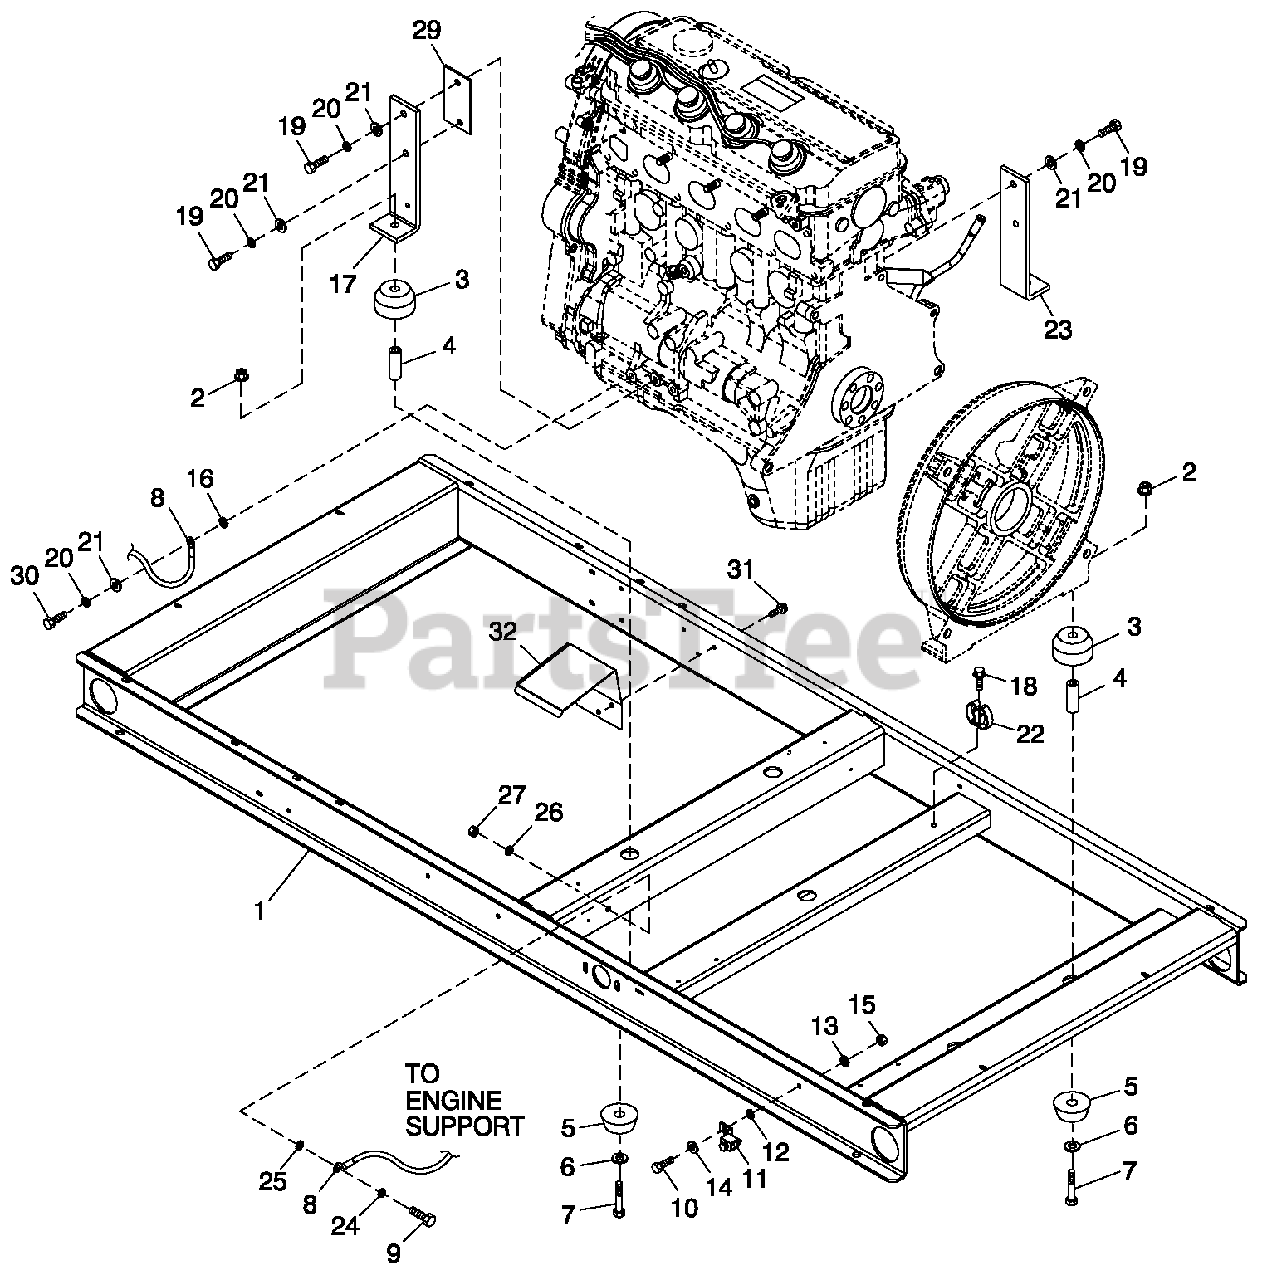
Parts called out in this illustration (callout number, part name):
1	WELDMENT FRAME 2.4L C2
2	NUT FLANGED HEX M12-1.75
3	DAMPENER VI BRATION 40 BLUE
4	SPACER .49 X .62 X 1.87 PWDR/ZNC
5	DAMPENER VI B RATION
6	WASHER FLAT M12
7	SCREW HHC M12-1.75 X 80 G8.8
8	ASSY WIRE 14.00"
9	SCREW HHC M8-1.25X 30 G8.8
10	SCREW HHC M6-1.0X 16 G8.8
11	LUGSLDLSS #2-#8X 17/64 CU
12	WASHER SHAKEPROOFINT1/4
13	WASHERLOCK M6-1/4
14	WASHER FLAT M6-1/4 ZINC
15	NUT HEX M6 -1.0G8YEL CHR
16	WASHER SHAKEPROOF INT 3/8
17	SUPPORT LH ENGINE 2.4L
18	SCREW HHTT M4-0.7X8BP
19	SCREW HHC M10-1.25 X 30 G8.8
20	WASHER LOCK 7/16
21	WASHER FLAT 3/8-M10 ZINC
22	SPRING CLIP HOLDER .37-.62
23	SUPPORT RH ENGINE 2.4L
24	WASHERLOCK M8-5/16
25	WASHER SHAKEPROOF INT 5/16
26	WASHER FLAT 5/16-M8 ZINC
27	NUT HEX M8-1.25 G8 CLEAR ZINC
29	SPACER ENGINE MOUNT (2.4L G1)
30	SCREW HHC M10-1.25 X 25 C8.8
31	SCREW HWHT M6-1 X 16 N WA Z/JS
32	HEAT SHIELD 2.4L G2
